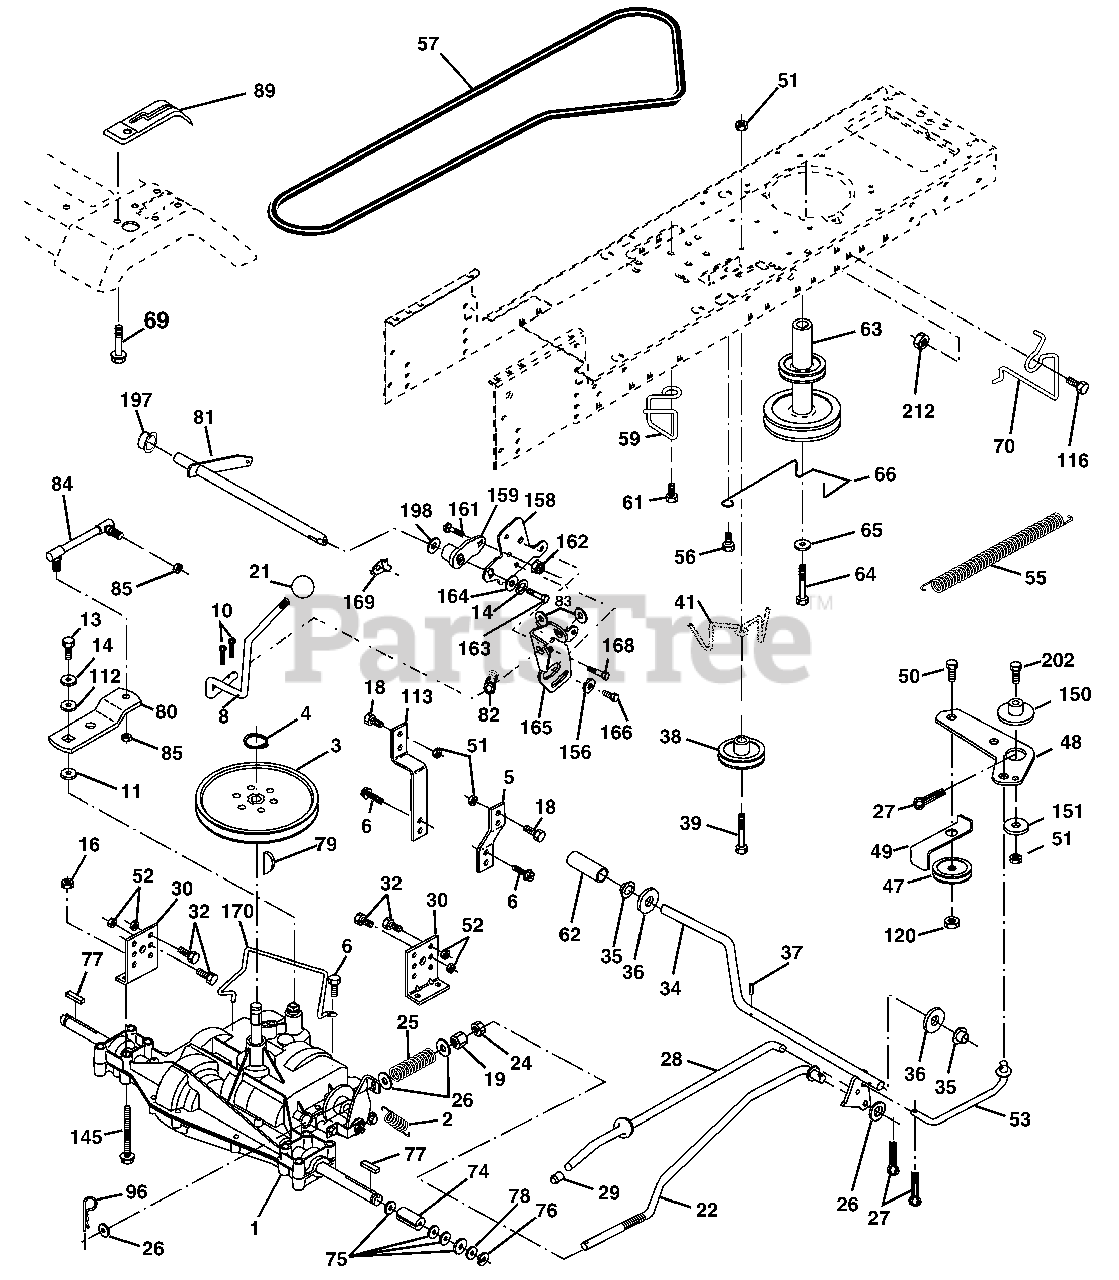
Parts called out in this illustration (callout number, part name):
2	Spring Return Brake T/a Zinc
3	Pulley Transaxle 18" tires
4	Ring Retainer # 5100-62
5	Strap Torque 30 Degrees
6	Screw 5/16-18 X 3/4
8	Rod Shift Fender Adjust Lt
10	Pin Cotter 1/8 X 1 Cad
11	Washer Plate Shf 388 Sq Hole
13	Bolt 1/4-28 Unf Gr 8 W/Patch
14	Washer Lock Hvy Helical
16	Nut Lock Hex w/ins 5/16-18
18	Bolt, Fin Hex 3/8-16 UNC x 1 Gr. 5
19	Nut Lock 3/8-16 Unc
21	Knob
22	Rod Brake Blk Zinc 26 840
24	Nut Hex Jam 3/8-16 Unc
25	Spring Rod Brake 2 00 Zinc
26	Washer 13/32 X 13/16 X 16 Ga
27	Pin Cotter 1/8 X 3/4 Cad
28	Rod Brake Parking LT/YT
29	Cap Brake Parking
30	Bracket Mtg Transaxle
32	Bolt Hex Hd 5/16-18unc X 3/4
34	Shaft Asm Pedal Foot
35	Bearing Nylon Blk 629 Id
36	Washer 21/32 X 1 X 16 Ga
37	Pin Roll 3/16 X 1"
38	Pulley Composite Flat
39	Bolt Fin Hex 3/8-16 unc X 3
41	Keeper Belt Flat Idler
47	Pulley Idler V Groove Plastic
48	Bellcrank Asm
49	Retainer Belt Style Spring
50	Bolt Hex Hd 3/8-16unc X 1-1/2
51	Nut Crownlock 3/8-16 Unc
52	Nut Crownlock 5/16-18 Unc
53	Link Clutch
55	Spring Return Clutch 6 75
56	Screw 3/8-16 x 1-1/4
57	V-Belt Ground Drive 95 25
59	Keeper Belt Span Ctr
61	Screw 3/8-16 x .875
62	Cover Pedal Blk Round
63	Engine Pulley
64	Bolt Hex
65	Washer Lock Hvy Hlcl Spr 7/16
66	Keeper Belt Engine Foolproof
69	Screw Hex wsh Hi Lo 1/4 x 1/2 unc
70	Guide Belt Mower Drive RH
74	Spacer Axle
75	Washer 25/32 X 1 1/4 X 16 Ga
76	E-ring #5133-75
77	Key Square 2 0 X 1845/ 1865
78	Washer 25/32 X 1-5/8 X 16 Ga
79	Key Woodruff #9 3/16 x 3/4
80	Arm Shift
81	Shaft Asm Cross Tapered PMST/20
82	Spring Torsion T/a
83	Washer 17/32 X 3/4 X 16 Ga
84	Link Transaxle PMST/20" Zinc
85	Nut Lock Center 1/4 - 28 FNTHD
89	Console Shift STLT
96	Retainer Spring 1"
112	Washer 9/32 x 3/4 x 10 Ga.
113	Strap Torque LT
116	Bolt Rdhd Sq Neck 3/8-16 x 1
120	Nut Lock Flg. 3/8-16 Unc
145	Bolt Hex FLGHD 5/16-18 Gr. 5
150	Spacer Retainer
151	Washer 13/32 x 2 x 10
156	Washer Srrted 5/16ID x 1.125
158	Bracket Shift Mount
159	Hub Shift
161	Bolt Rdhd Sqnk 1/4-20 x 3/4 Gr
162	Nut Crownlock 1/4-20 Unc
163	Bolt Hex Fin 1/4-20 Unc x 1 Gr 5
164	Washer 5/8 x .281 x 10 Ga
165	Bracket Pivot Lever
166	Screw 5/16-18 x 5/8
168	Bolt Shoulder 5/16-18 x .561
169	Plate Fastening
170	Keeper Belt Transaxle Gear
197	Nyliner Snap-In
198	Washer Nyliner
202	Bolt Carr Sh 3/8-16 x 1-3/4 Gr. 5
212	Nut Hexflange Lock
